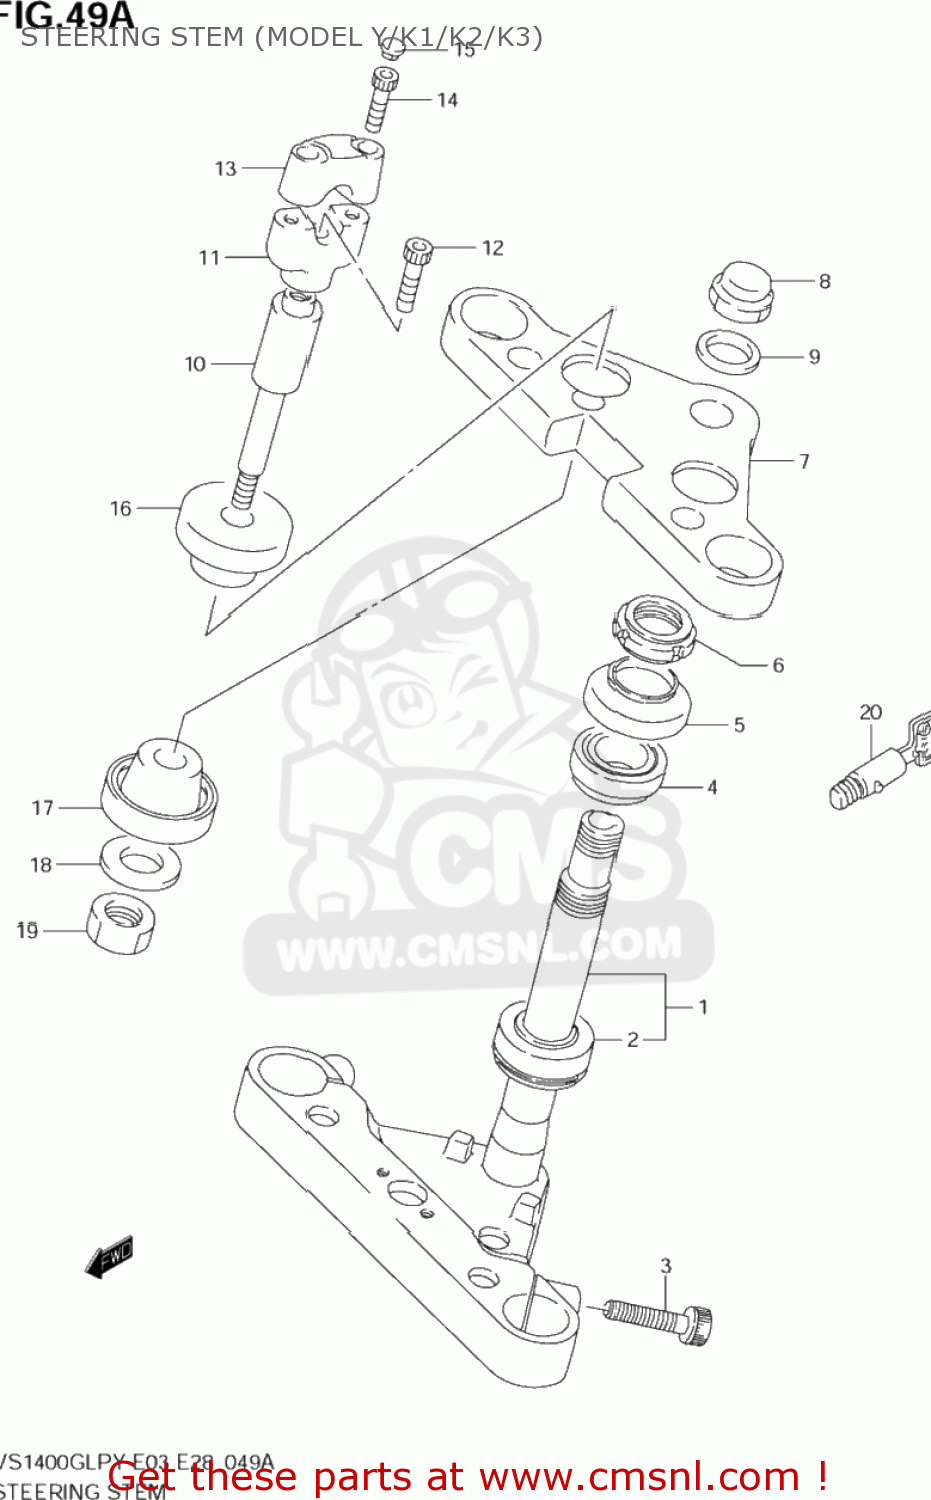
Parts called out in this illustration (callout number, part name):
1	STEM,STEERING
2	BEARING(30X55X17)
3	BOLT
4	BEARING(25X47X15)
5	SEAL,STEERING UPR DUST
6	NUT,STEERING STEM(25X44X10)
7	BRACKET,FR FORK UPR
8	NUT,CAP
9	WASHER(22.5X32X1.6)
10	STAY,HANDLE
11	HOLDER,HANDLE LWR
12	BOLT
13	HOLDER,HANDLE UPR
14	BOLT
15	CAP(OD:14.5)
16	DAMPER,RUBBER
17	CUSHION,RUBBER UNDER
18	WASHER
19	NUT
20	LOCK SET,STEERING
